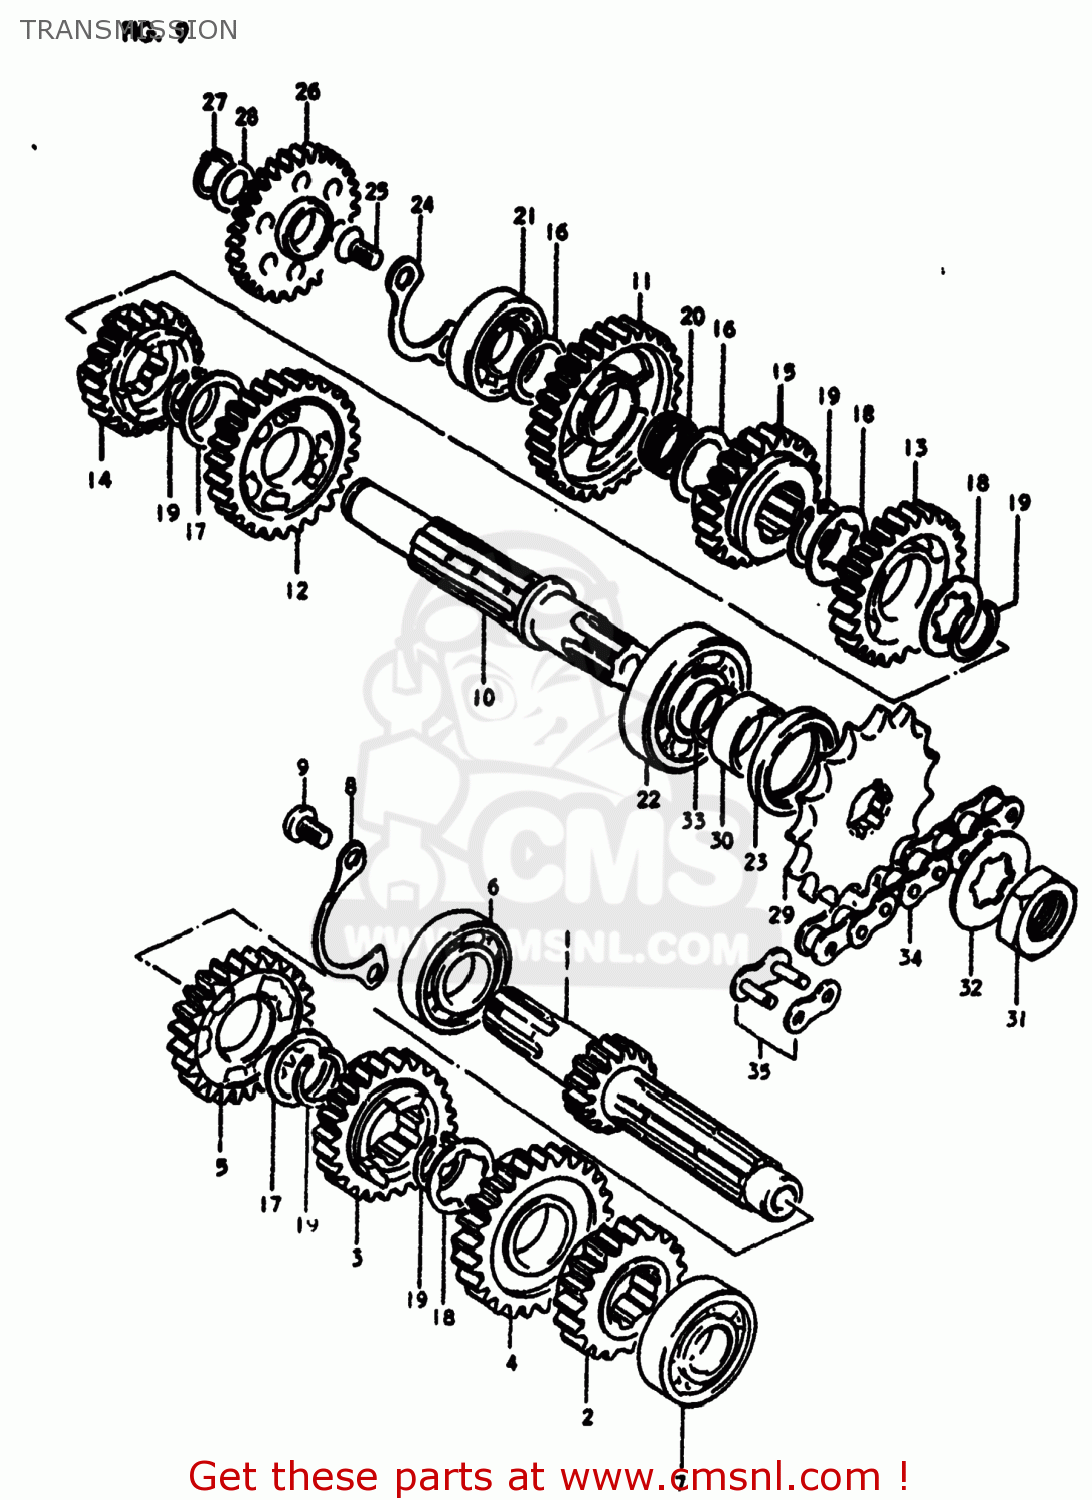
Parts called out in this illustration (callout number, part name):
1	SHAFT,COUNTER
2	GEAR,SECOND DRIVE
3	GEAR,THIRD DRIVE
4	GEAR,FOURTH DRIVE
5	GEAR,FIFTH DRIVE
6	BEARING
7	BEARING
8	PLATE,COUNTERSHAFT BEARING
9	SCREW 6X12
10	SHAFT,DRIVE
11	GEAR,FIRST DRIVEN
12	GEAR,SECOND DRIVEN
13	GEAR,THIRD DRIVEN
14	GEAR,FOURTH DRIVEN
15	GEAR,FIFTH DRIVEN
16	WASHER
17	SHIM(22X28X0.5)
18	WASHER,LOCK
19	CIRCLIP
20	BEARING(17X21X9.8)
21	BEARING
22	BEARING
23	SEAL,OIL(32X42X6)
24	PLATE,DRIVESHAFT BEARING
25	SCREW
26	GEAR,KICK STARTER IDLE
27	CIRCLIP
28	WASHER
29	SPROCKET,ENGINE
30	SPACER(22X32X11.5)
31	NUT
32	WASHER,LOCK
33	O RING(D:1.7,ID:22)
34	CHAIN ASSEMBLY,DRIVE
35	JOINT ASSEMBLY,CHAIN
